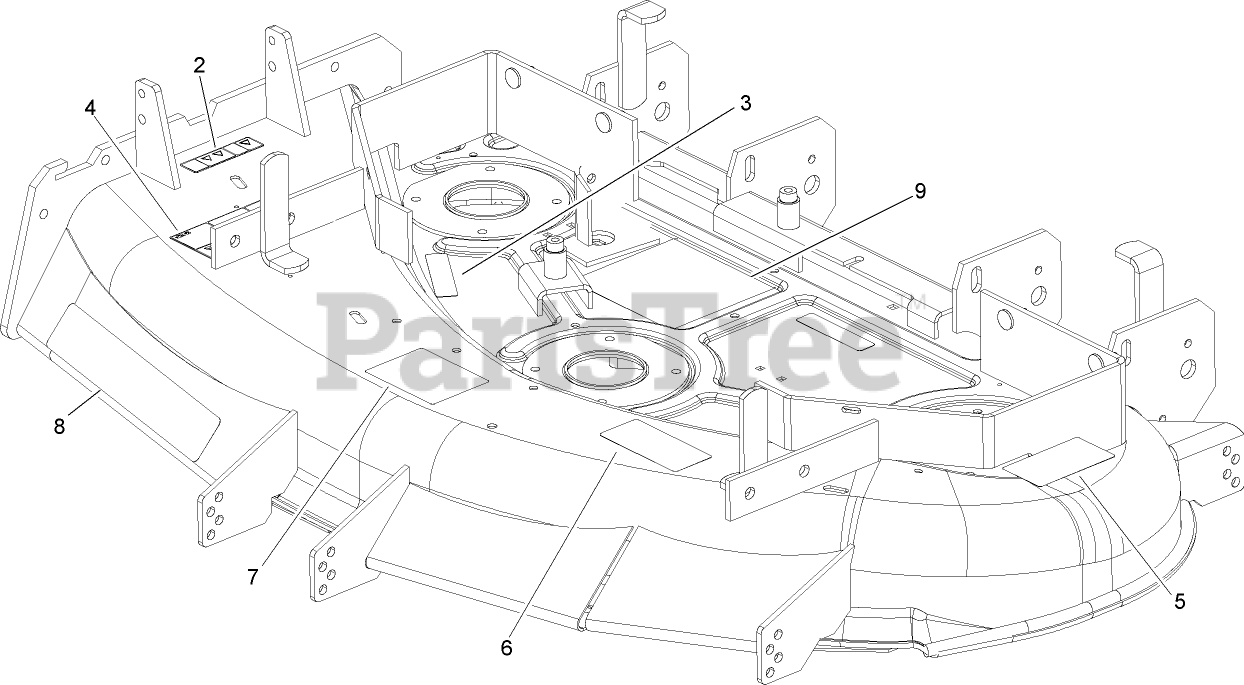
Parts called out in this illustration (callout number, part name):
2	DECAL-WARNING, DEFLECTOR
3	DECAL-WARNING
4	DECAL-DANGER
5	DECAL-DANGER
6	DECAL-TORQUE, BLADE BOLT
7	DECAL-ANTI SCALP
9	DECAL-SERVICE AID, BELT ROUTING
